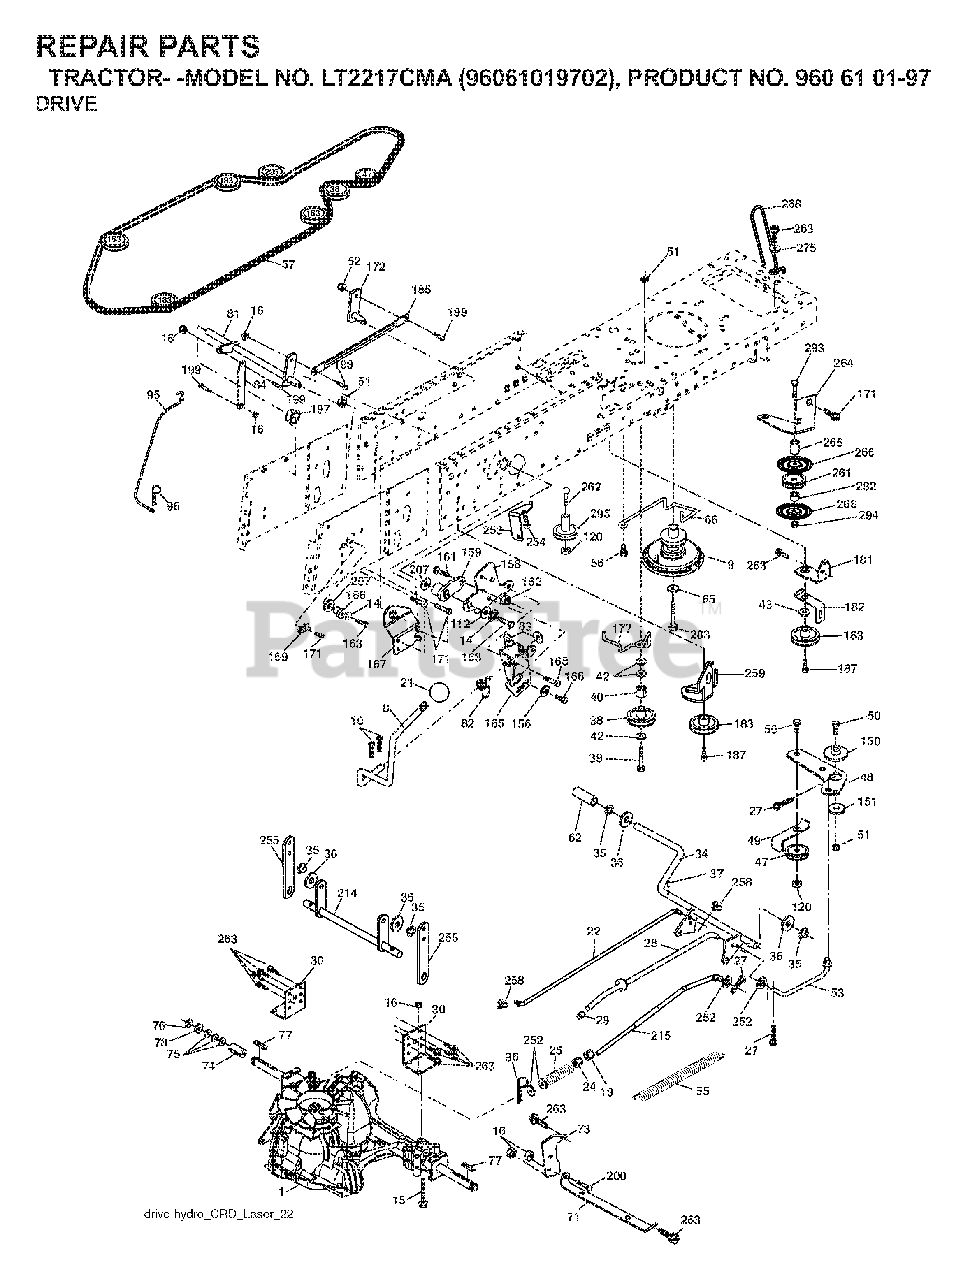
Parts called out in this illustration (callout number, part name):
8	ROD SHIFT FENDER ADJUST LT
10	PIN COTTER
14	LOCKWASHER
15	BOLT HEX 5/16-18 GR 5
16	NUT.71038.31-18.HEX.NYLOCK
19	NUT
21	PISTOL KNOB
24	NUT
27	COTTER PIN
28	ROD, PARKING BRAKE
29	PLUNGER CAP
30	BRKT, TRNSXLE MNT 20"
34	SHAFT, FOOT PEDAL
35	BEARING.NYLON
36	WASHER LT
37	DRIVE PIN
38	PULLEY.FLAT
42	WASHER
47	IDLER PULLEY
48	BELLCRANK, CLUTCH
49	RETAIN BELT
50	BOLT.3/8-16X1.50
51	LOCKNUT
52	LOCKNUT
53	LINK.CLUTCH.7.66.2005
55	SPRING, RETURN LT
56	SCREW.3/8-16
62	PEDAL COVER T
65	LOCKWASHER
66	KEEPER BELT ENGINE
71	STRAP TORQUE LH HYDRO
73	STRAP TORQUE RH HYDRO
74	SPACER AXLE
76	E-RING LT
77	SQUARE KEY
81	SHAFT ASSY
82	SHIFT SPRING
83	WASHER
96	RETAINER M
112	WASHER LT
120	NUT LOCK FLG 3/8-16 UNC
150	BUSHING.BELLCRANK.GRD.DR
151	WASHER 12/32X2X10GA
156	WASHER.SRRTD.5/16
158	BRACKET
159	HUB.SHIFT
161	BOLT
162	NUT.CROWNLOCK.1/4
165	RP BRACKET
167	BRACKET
168	BOLT.SHOULDER.5/16-18X
169	PLATE.FASTENING.CROSS.SHAFT
187	BOLT.5/16-18X1.25
197	NYLINER SNAP 5/8" ID
199	BOLT SHOULDER 5/16-18 UNC
200	BOLT
207	WASHER NYL
254	SCREW 3/8-16X1
258	CLIP RETAINER
261	FLAT IDLER PULLEY
263	SCREW, 3/8-16X3/4
275	WASHER
294	NUT, HEX 3/8-16
295	PULLEY IDLER COMPOSITE
